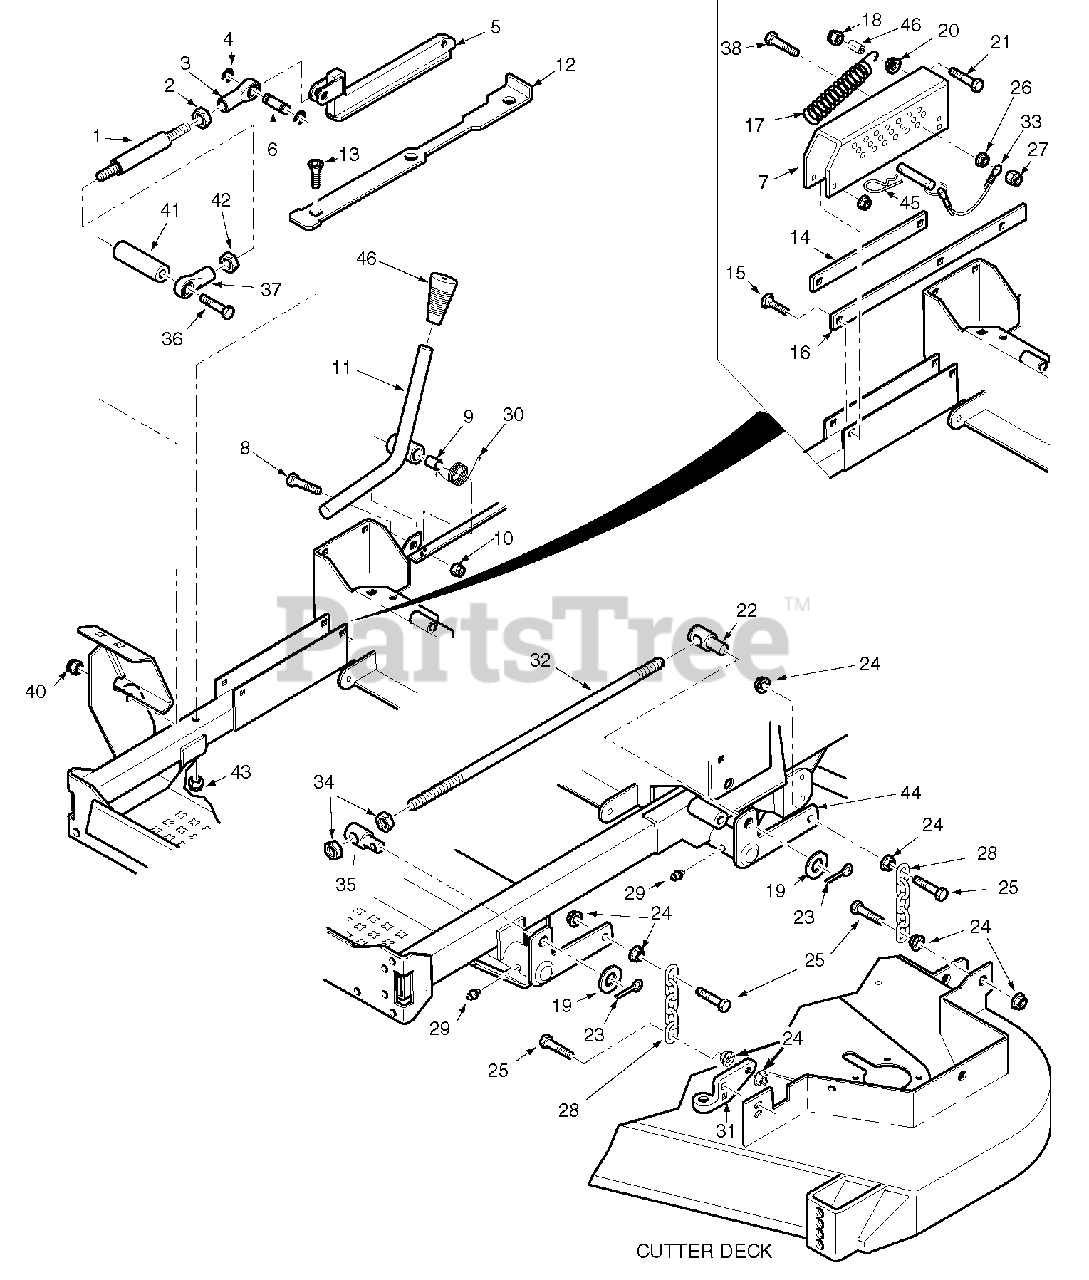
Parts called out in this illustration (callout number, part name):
1	Rod, Deck Lift Linkage
2	Nut, Jam 1/2-20 LH Thread
3	Rod End, 1/2-20 Female Thread
4	Retaining Ring, 1/2" External "E"
5	Slide, Deck Height Adjust
6	Pin, Deck Lift
7	Bracket, Cutting Height Adjustment
8	Bolt, Hex Head 3/8-16 x 2-3/4"
9	Bushing .502" OD
10	Nut, Elastic Stop 3/8-16
11	Lever, Deck Latch
12	Slide, Cutting Height
13	Screw, Cap 5/16-18 x 3" FHHS
14	Guide, Short
15	Bolt, Carriage 5/16-18 x 1"
16	Guide, Long
17	Spring, Helper
18	Nut, 3/8-16 Center Lock
19	Flatwasher, 5/8-.656 x 1.312 x .095"
20	Nut, 3/8-16 Serr. Flange
21	Bolt, Hex Head 3/8-16 x 1-1/4"
22	Swivel Joint LH
23	Cotter Pin, 3/16 x 1"
24	Nut, Serr. Flange 3/8-16
25	Bolt, Hex Head 3/8-16 x 1-1/2"
26	Nut, Serr. Flange 3/8-16
27	Nut, Elastic Stop 3/8-16
28	Chain
29	Grease Fitting, 1/4-28 Self Tap
30	Torsion Spring
31	Lever Assy., Deck Level
32	Stud, 1/2-13 x 20"
33	Lanyard
34	Nut, 1/2-13
35	Swivel Joint RH
36	Bolt, Hex Head 1/2-13 x 5"
37	Rod End, 1/2-20 Female RH Thread
38	Bolt, Hex Head 3/8-16 x 3-1/2"
39	Spacer
40	Locknut, 1/2-13
41	Spacer
42	Nut, 1/2-20 UNF-2B
43	Nut, Elastic Stop 5/16-18
44	Lift Bellcrank Weldment, LH Rear
44	Lift Bellcrank Weldment, RH Rear
44	Flatwasher, 1.0-1.062 x 1.5 x .048"
44	Retaining Ring, 1" ext.
45	Hair Pin Cotter, .177 x 3-1/4"
46	Grip, Deck Latch Lever
